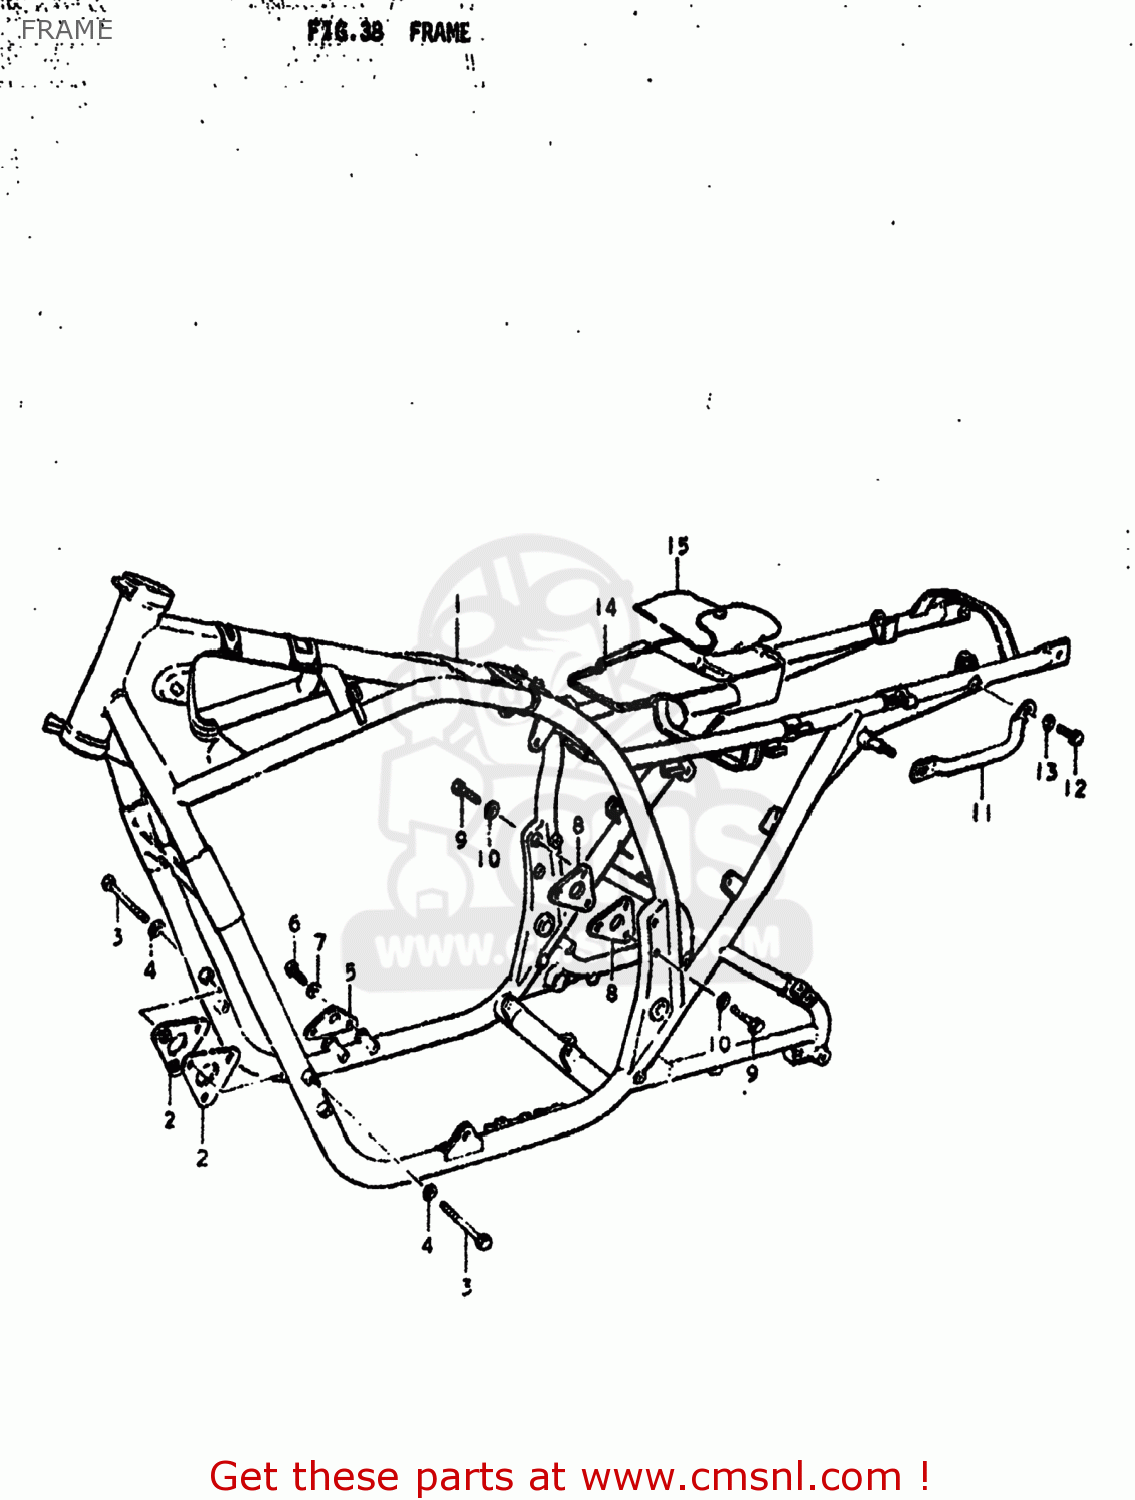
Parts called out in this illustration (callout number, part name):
1	FRAME
2	PLATE,ENGINE MOUNTING
3	BOLT
4	LOCK WASHER
5	PLATE,ENGINE MOUNTING
6	BOLT
7	LOCK WASHER
8	PLATE,ENGINE MOUNTING
9	BOLT 8X40
10	LOCK WASHER
11	GRIP,FRAME HANDLE
12	BOLT
13	WASHER
14	HOLDER,TOOL
15	TOOL SET
